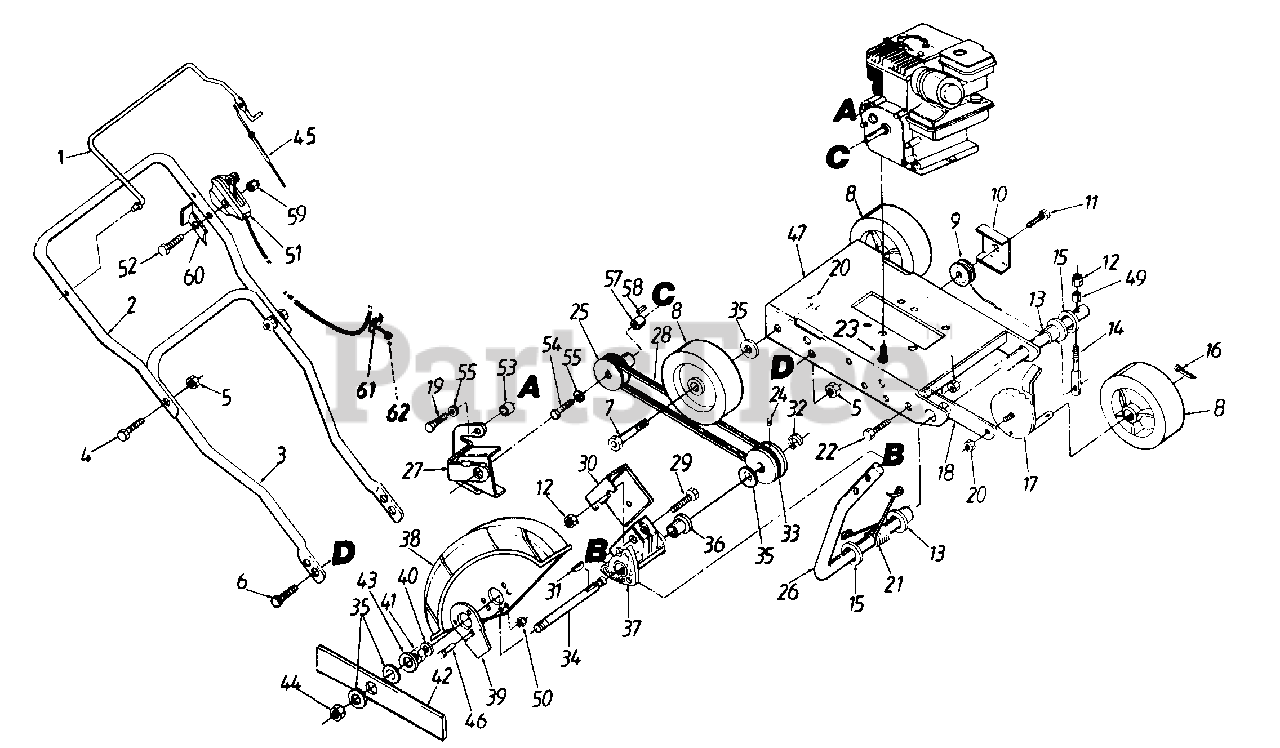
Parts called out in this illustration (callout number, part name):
1	Control Handle
2	Upper Handle
3	Lower Handle
4	Hex Bolt 5/16-18 x 1.5"
5	Hex L-Nut 5/16-18 Thd.
6	Hex Bolt 5/16-18 x .625"
7	Wheel Bolt
8	Wheel - 6"
9	Idler Pulley
10	Bracket - Idler Pulley
11	Bolt (Special)
12	Hex L-Nut 5/16-18 Thd.
13	Bushing
14	Arm-Pivot Rod
15	Flat Washer 5/8" I.D.
16	Cotter Pin 1/8 x 3/4"
17	Adjuster Assembly (Depth)
18	Arm - Front Wheel
19	Hex Bolt 5/16-24 x 1" (Gr. 5)
20	Hex Keps L-Nut 3/8-16 Thd.
21	Spring - Cutterhead
22	Hex Bolt 5/16-18 x 1" Lg.
23	Engine Bolt (Special)
24	Locking Set Scr. 5/16-18
25	Engine Pulley
26	Rod - Cutterhead
29	Hex Bolt 5/16-18 x 1.5"
30	Belt Guard (Cutterhead)
31	Woodruff Key
32	Retaining Ring
33	Pulley - Cutterhead
34	Shaft - Cutterhead
35	Bell-Wash. 3/8" I.D.
36	Bushing - Cutterhead
37	Housing - Cutterhead Shaft
38	Blade Guard
39	Edge Guide
40	Flat Washer .035 Thk.
41	Heavy Hex Jam Nut 3/8-24
42	9" Replacement Blade
43	Fl-Wash. 3/8" I.D.
44	Hex Nut 3/8-24 Thd.
45	Cable - Depth Control
46	Hex Self-Tap Scr. #10-24
47	Base - Edger Frame
49	Spacer - Pivot Arm
50	Nylok Nut #10-24
51	Throttle Control
52	Hex Bolt 1/4-20 x 1.75" Lg.
53	Spacer
54	Hex Bolt 3/8-24 x 1.75"
55	L-Wash 5/16" I.D.
57	Spacer
58	Sq. Key 3/16" x 1.5"
59	Hex L-Nut 1/4-20 Thd.
60	Stop Bracket
61	Cable Clamp
62	Hex Tap Scr. #8 x .5"
